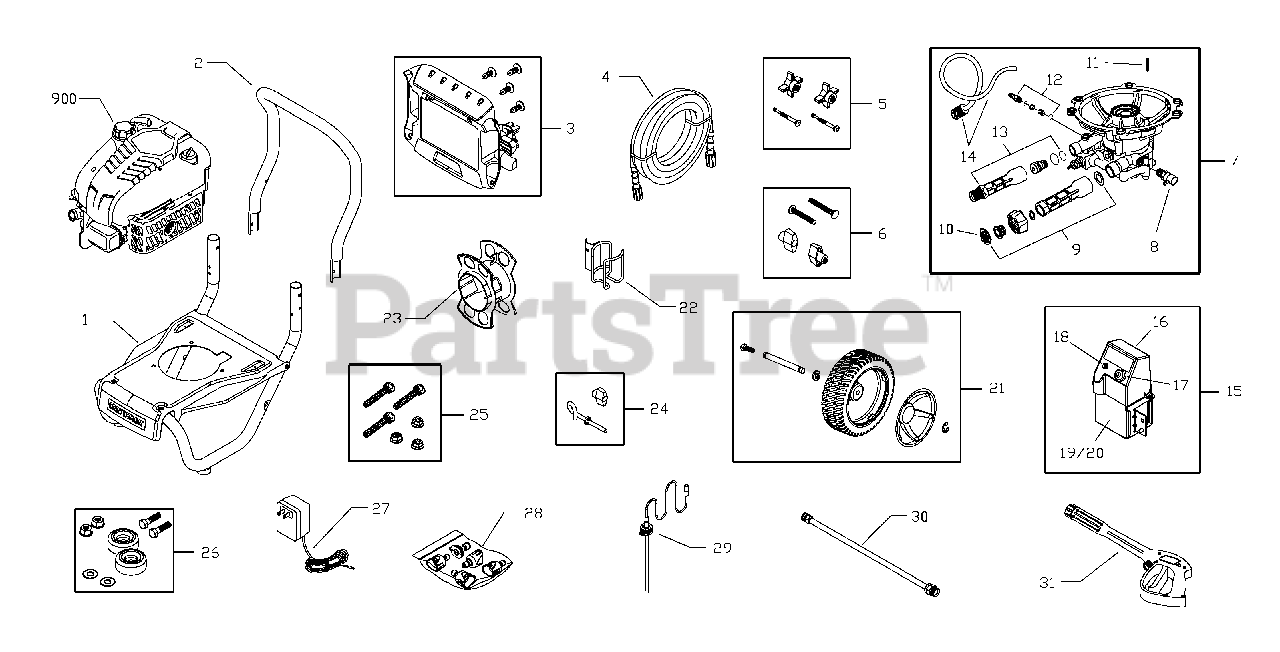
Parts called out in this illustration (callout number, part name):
1	Base, w/Vib Mounts
3	Kit, Billboard w/Clips & Decals
4	Hose
7	Assy, Pump
8	Valve, Thermal Relief
9	Kit, Water Inlet
12	Kit, Chemical Injection
13	Kit, Water Outlet
14	Kit, Chemical Hose/Filter
15	Assy, Battery Electric Start
16	Switch Cover
18	Coaxial Jack, DC
19	Weldment, Battery Holder
20	Battery
22	Wireform
24	Kit, Rope Guide
25	Kit, Pump Mounting Hardware
26	Kit, Vibration Mount
27	Charger, Battery
30	Extension, QC
31	Gun
900	Engine
